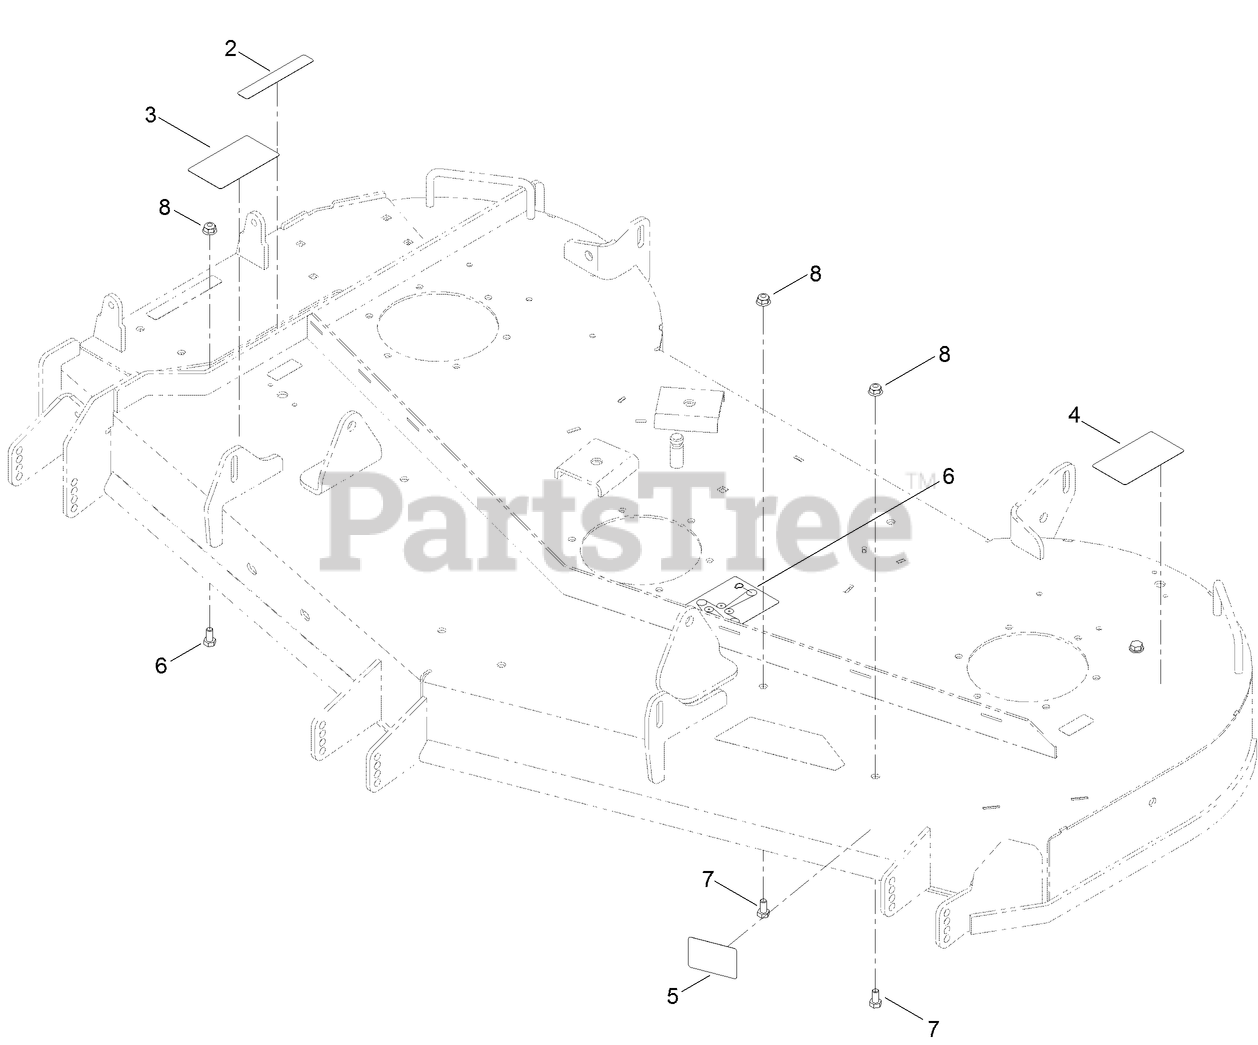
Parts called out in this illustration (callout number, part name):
2	DECAL-DANGER
3	DECAL-DANGER
4	DECAL-DANGER
5	DECAL-SCALP, ANTI
6	DECAL-ROUTING, BELT
7	SCREW-HH
8	NUT-HF, NI
